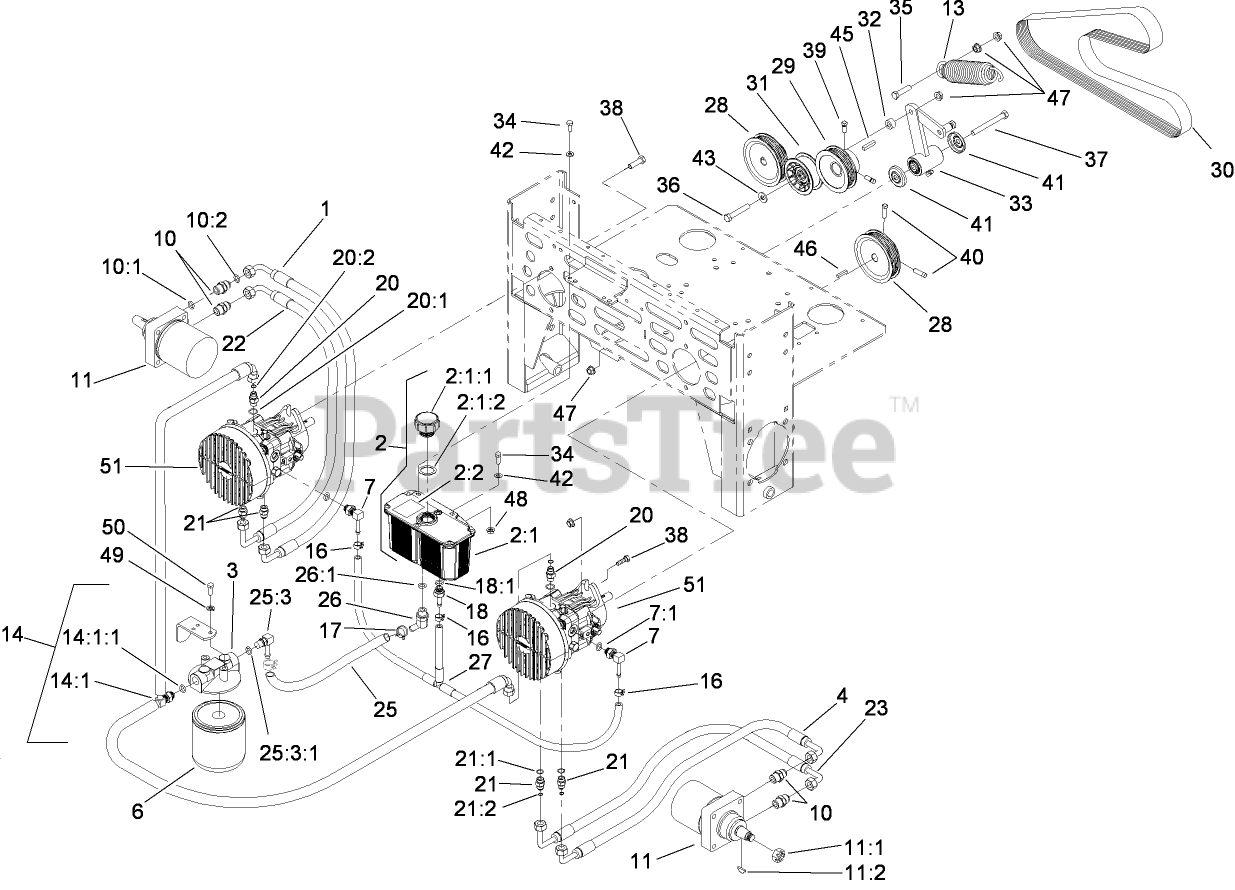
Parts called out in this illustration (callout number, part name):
1	HYD HOSE ASM
2	HYD Reservoir ASM
2:1	Reservoir-HYD
2:1:1	CAP-RESERVOIR, HYD
2:1:2	GASKET-CAP
2:2	DECAL-TANK, HYD
3	HEAD-FILTER
4	HYD HOSE ASM
6	FILTER-OIL, HYD (WINTER)
6	FILTER-OIL, HYD
7	ELBOW-90 DEG
7:1	O-RING
10	Fitting-Straight
10:1	O-RING
10:2	O-Ring
11	MOTOR-WHEEL
11:1	NUT-HH
11:2	KEY-WOODRUFF
13	Spring-Extension
14	HYD HOSE ASM
14:1	ADAPTER-RUN, TEE
14:1:1	O-RING
16	Clamp-Hose
17	Clamp-Hose
18	Adapter-Straight
18:1	O-RING
20	FITTING-STRAIGHT
20:1	O-Ring
20:2	O-RING
21	FITTING-STRAIGHT
21:1	O-RING
21:2	O-Ring
22	HYD HOSE ASM
23	HYD HOSE ASM
25	HYD HOSE ASM
25:3	FITTING-BARB
25:3:1	O-RING
26	FITTING-BARBED, 45 DEG
26:1	O-RING
27	HYD Hose ASM
28	SHEAVE
29	SHEAVE
31	PULLEY-FLAT IDLER
32	SPACER
33	PUMP IDLER ASM
34	SCREW-HH
35	SCREW-HH
36	SCREW-HH
37	SCREW-HH
38	SCREW-HH
39	SCREW-SET
40	SCREW-SET
41	GUARD-TOP
42	WASHER-FLAT
43	WASHER-FLAT
45	KEY-SQUARE
46	KEY-SQUARE
47	NUT-HHF, WHIZ
48	NUT-HF
49	WASHER-LOCK
50	SCREW-HH
51	PUMP-HYD, 12CC W/FAN
